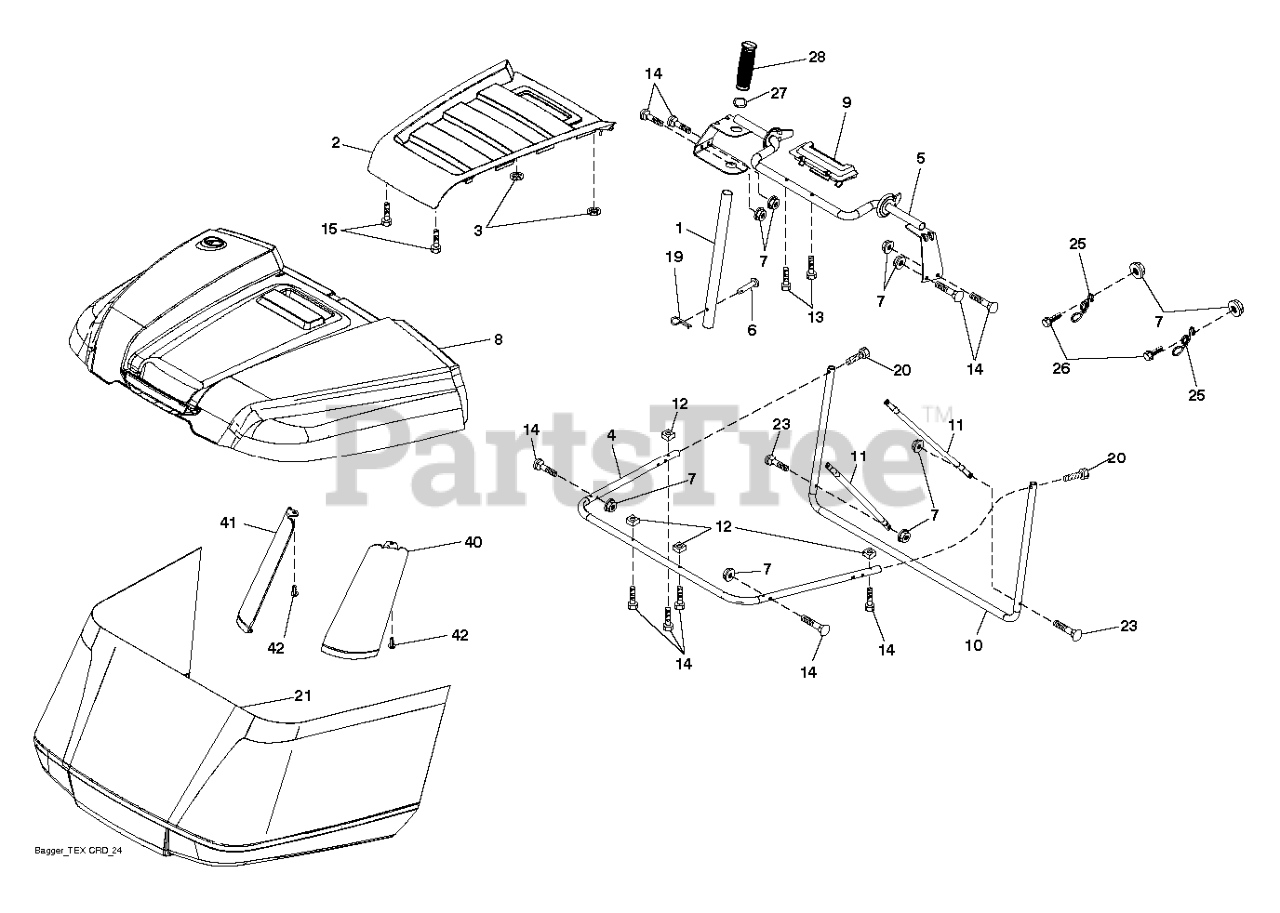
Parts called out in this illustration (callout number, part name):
1	TUBE.HANDLE.BAGGER.CRD/SRD.BLA
2	APPLIQUE.TOP.BAG.SRD.ORANGE
3	NUT.PUSH.156
4	SUBASM.TOP.TUBE.TEX.CRD
5	FRAME.ASM.TOP.BAGGER.SRD
6	RIVET,DRILLED
7	NUT T
8	BAGGER.TOP.SRD.APPLIQUE
9	INSERT.HANDLE.BAGGER.(2 2)
10	FRAME FRAME.FRONT.TEX.CRD
11	BRACE BRACE SIDE TUBE
12	NUT.SQUARE.1/4
13	SCREW.1/4X1.150.HXWSH
14	BOLT.SHOULDER.HX.WSH.1/4X1.150
15	SCREW,#8.FLAT.HEAD.DRILL.TIP
19	PIN.COTTER.5/16.BOW TI
20	SCREW.HEXCAP.1/4-20X1.375(2 2)
25	SPRING.LATCH.BAGGER.SRD
26	SCREW HEX CRT
27	RB GROMMET.RUBBER.SRD
28	GRIP.HANDLE.BLACK
42	CLIP CHRISTMAS TREE CLIP
